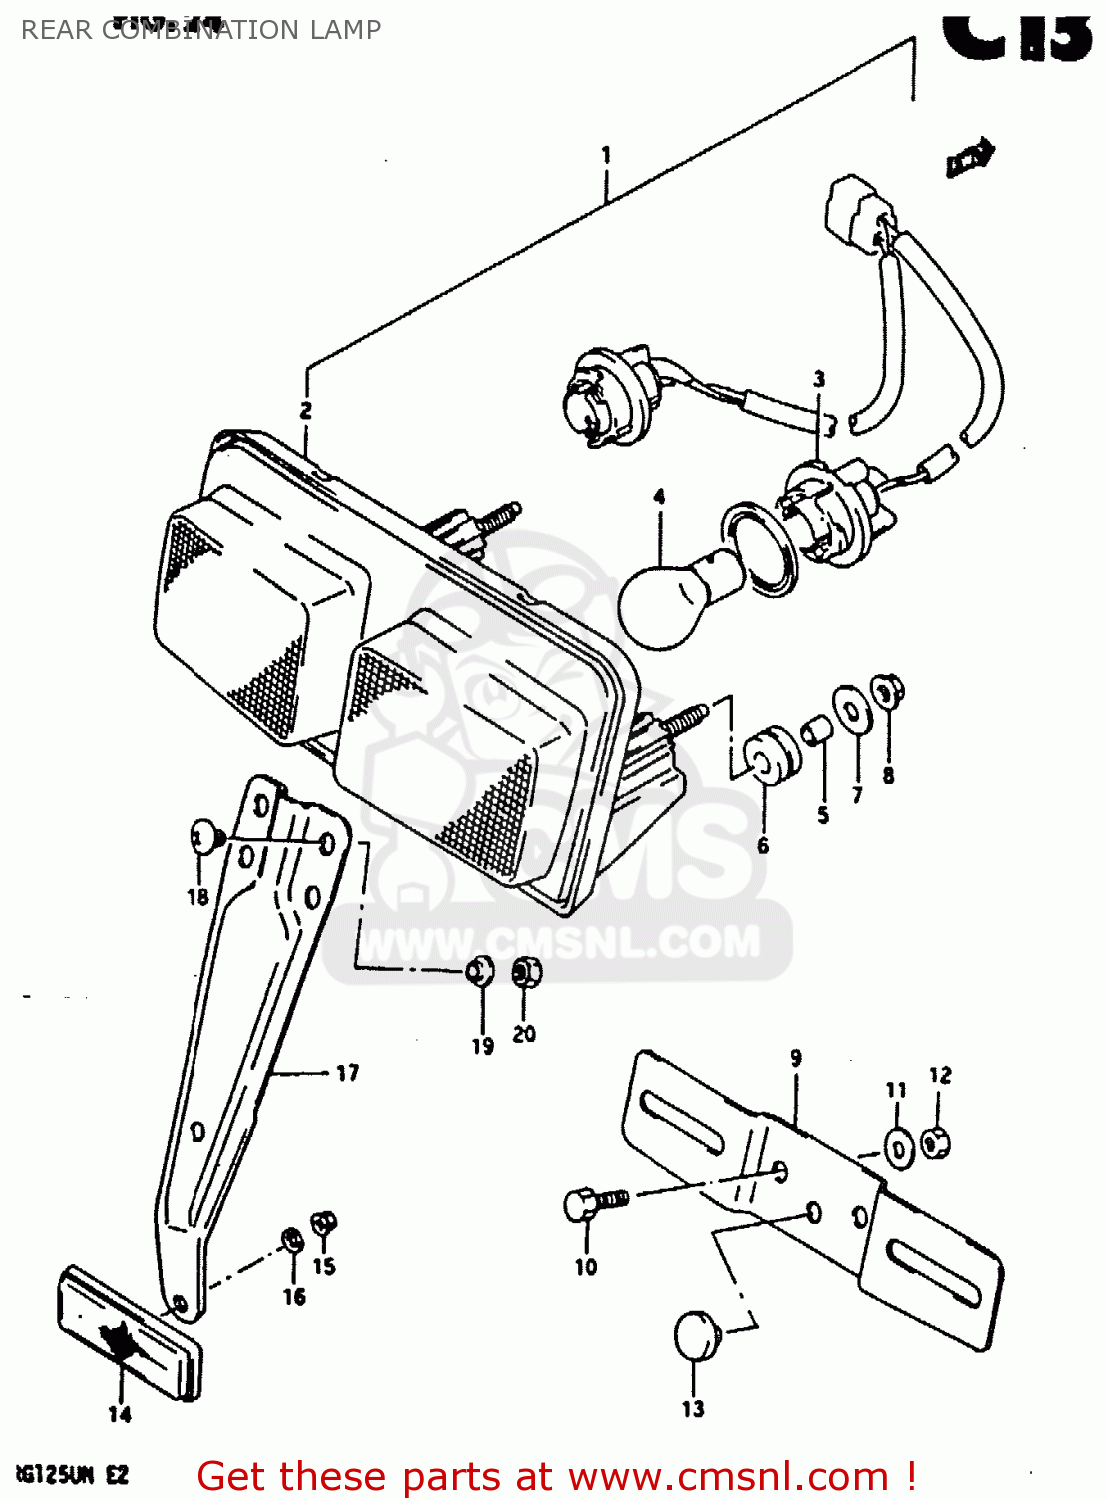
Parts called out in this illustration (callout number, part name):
1	LAMP ASSY,RR C
2	LAMP UNIT
3	SOCKET,RR COMB
4	BULB(12V21/5W)
5	SPACER (6.1X8X9.5)
6	CUSHION
7	WASHER(6.5X18X1)
8	NUT 6MM
9	PLATE,RR LICENSE
10	BOLT
11	WASHER,COVER,FRONT
12	NUT
13	CUSHION
14	REFLEX REFLECTOR,RR
15	NUT
16	WASHER
17	BRACKET,RR REFLEX REFLECTOR
18	SCREW, BRACKET
19	WASHER
20	NUT
